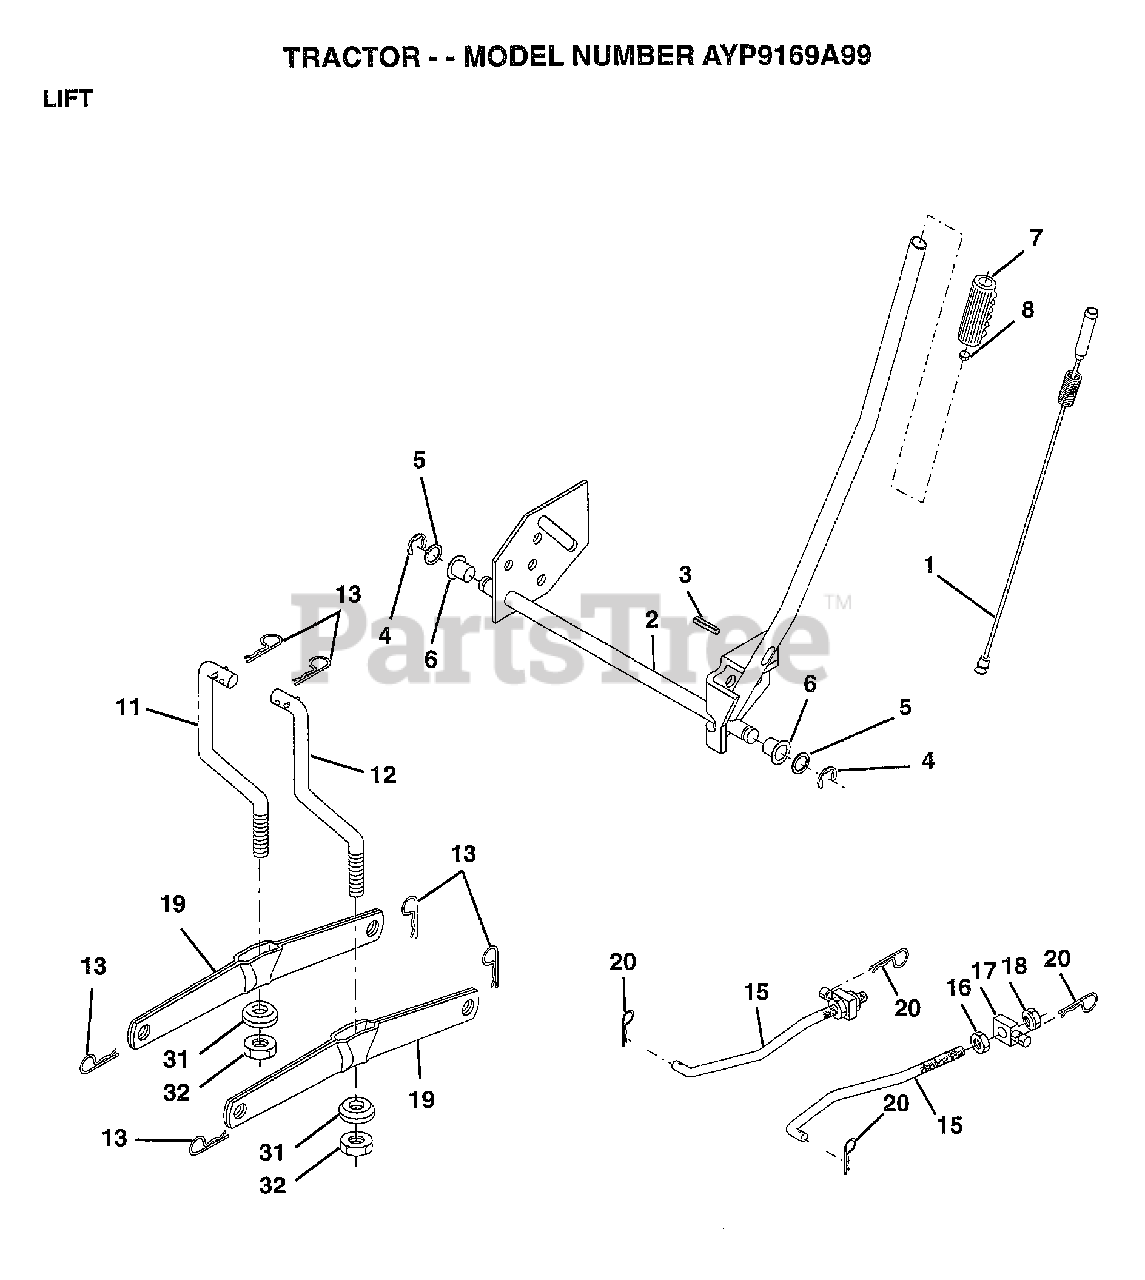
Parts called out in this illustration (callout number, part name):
1	WIRE ASM W.SPRING
2	"SHAFT ASM LIFT,RH"
3	PIN-GROOVE LT
5	WASHER
6	NYLON BEARING
7	GRIP
15	LINK.FRONT
16	NUT
17	TRUNION
18	NUT.LK.W/WSH.1/2.
19	ARM SUSP REAR
20	RETAINER SPRING
31	BEARING PVT LH
32	NUT.CROWNLOCK.3/8
